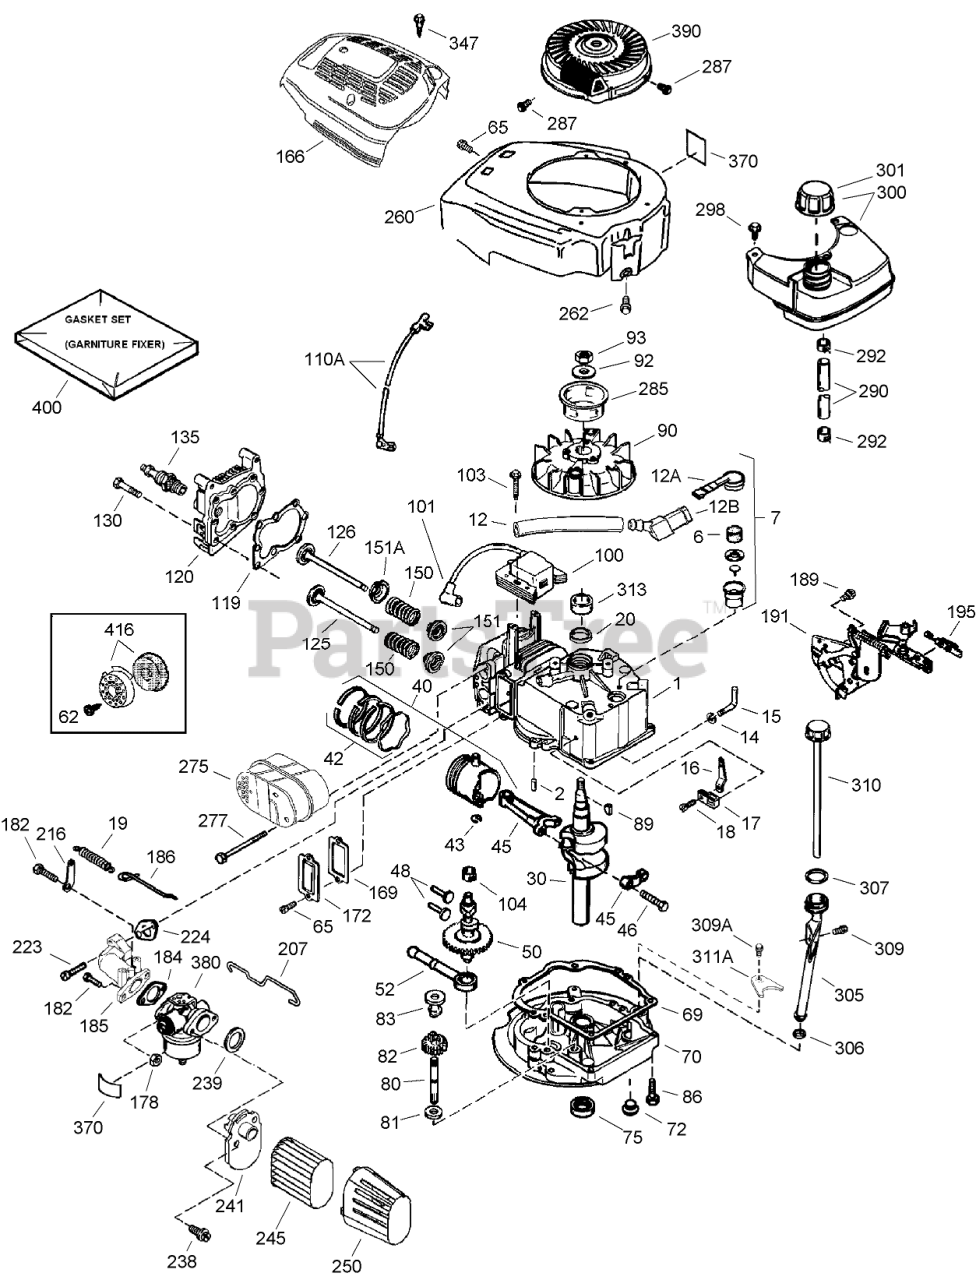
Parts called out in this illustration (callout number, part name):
370	Decal-Warning
370	Decal-Primer
370	Decal-Lubrication
380	Carburetor ASM
390	Rewind Starter ASM
400	Gasket Set
416	Spark Arrestor Kit
